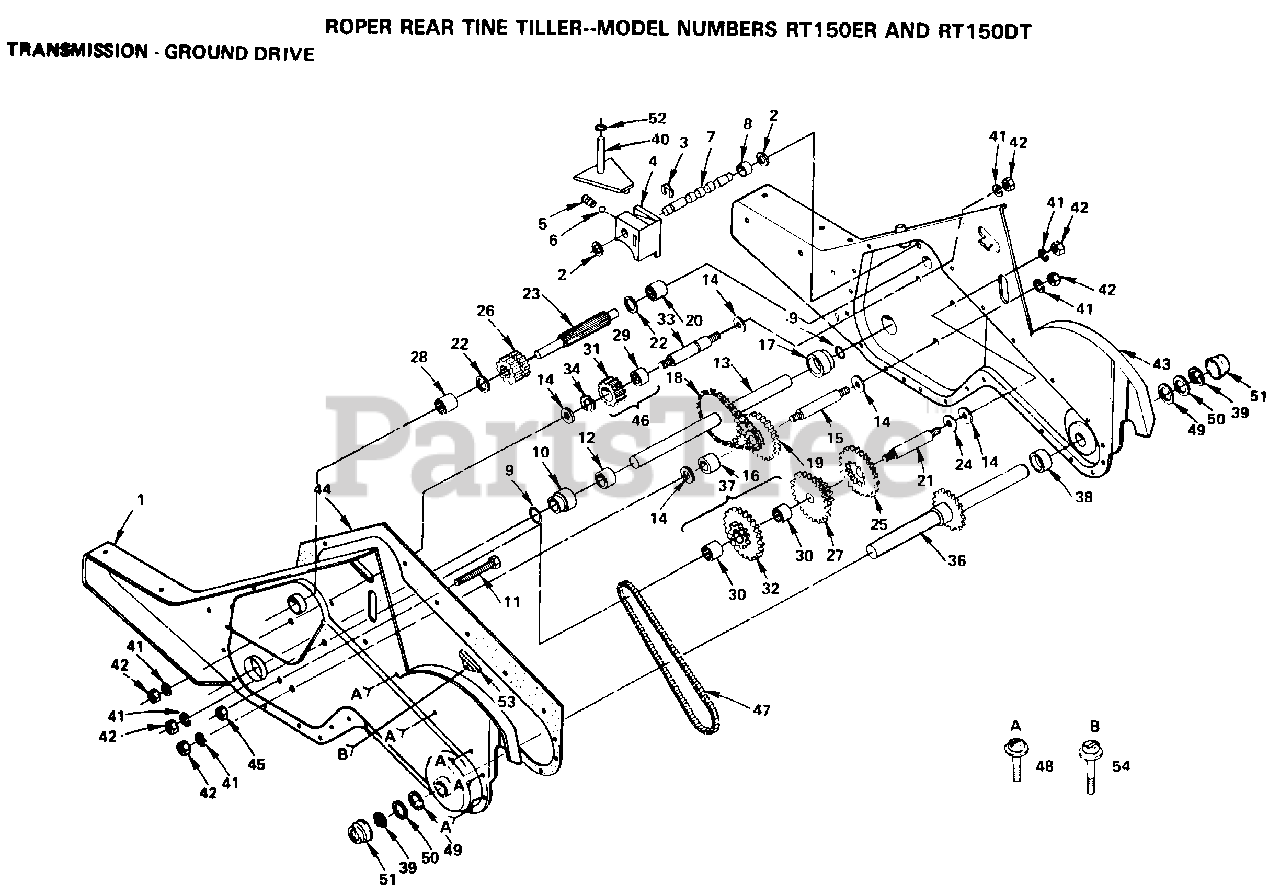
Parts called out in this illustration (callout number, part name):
2	WASHER SEAL CRT
3	KLIP RING
4	SHIFT FORK TI
5	SPRING-SHIFT CRT
7	SHAFT SHIFT CRT
8	SPACER SPLIT CRT
9	O RING CRT
10	"CRT, BEARING"
11	SCRW WHIZ LOK CRT
12	BUSHING TI
14	WASHER
15	SHFT 2ND RED. CRT
16	SPACER TI
18	CHAIN CRT
19	SPRCKT 8 GEAR CRT
20	"TI, BEARING"
21	REDUCTION SHFT TI
22	"T, BEARING"
23	SHAFT-INPUT CRT
24	BRNG RACE
25	GEAR TI
26	PINION-INPUT CRT
27	GEAR TI
28	NEEDLE BRNG LT
29	NEEDLE BEARING TI
30	BEARING
31	GEAR-REV IDLR CRT
33	SHAFT CRT
34	KLIP RING
36	SHAFT ASSY TI
38	SPACER TI
39	RING SPIRAL CRT
40	ARM ASSY CRT
41	LOCKWASHER
42	NUT.ASF.HEX.7/16
44	GASKET TI
45	NUT.HEX.5/16-18
45	GEAR ASSY CRT
46	GEAR ASSY CRT
47	CHAIN.50 LINK TI
48	SCREW CRT
51	CUP.FORMED.
52	O-RING TI
